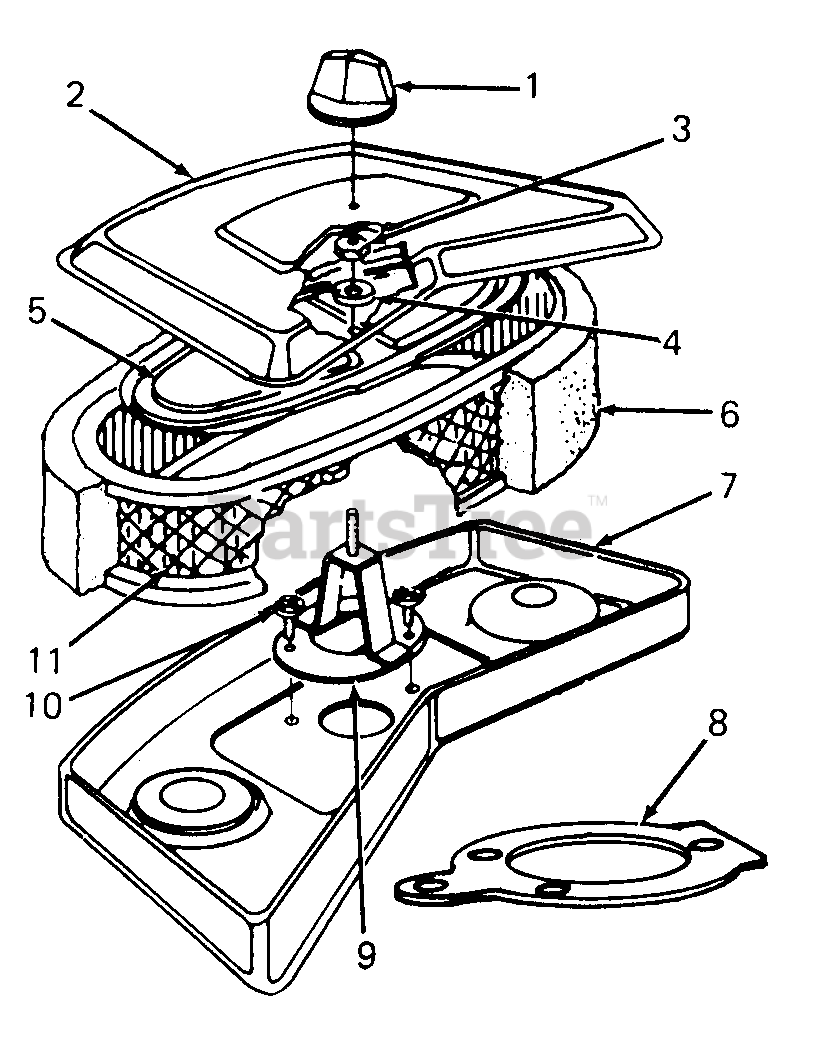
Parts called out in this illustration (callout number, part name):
1	Knob
3	Nut, Hex
5	Cartridge Plate
6	Element
9	Mounting Strap Assy
10	Screw, Sem
11	Cartridge
